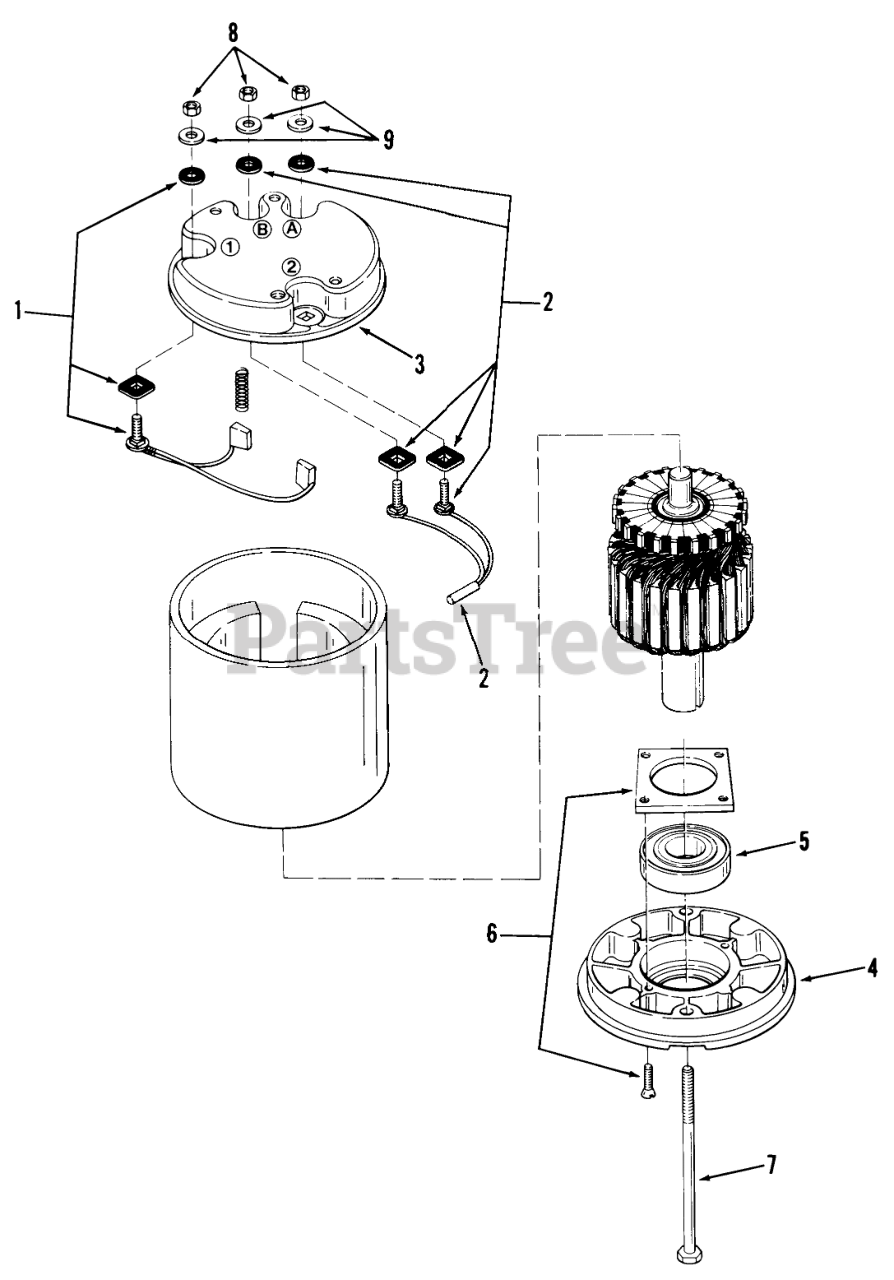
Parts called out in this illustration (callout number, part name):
1	Brush Pair W/Springs & Fiber Washers
2	Thermostat W/Washer
3	End Bell-Comm. End
4	End Bell-Drive End
5	Ball Bearing
6	Retainer-Drive End (W/Screws)
7	Bolt 5/16-18 X 7 1/4
8	Nut
